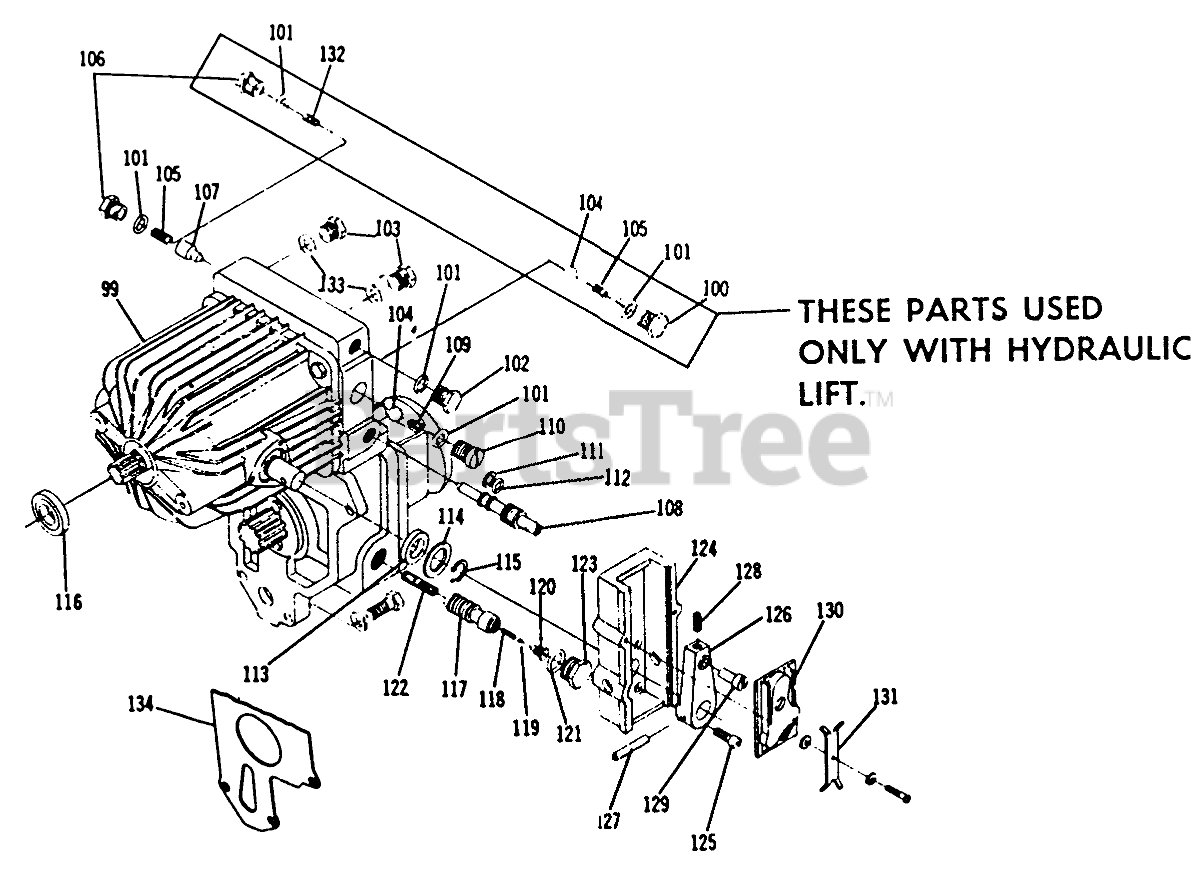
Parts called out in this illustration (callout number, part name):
99	SRV BULLT 437B
101	O RING
111	O-RING
126	Arm-Cam Follower
128	Set Screw-1/4-20 x 1/2
130	CAM
131	Screw #8-32 x 1/2
131	Lockwasher
131	Washer
133	O RING
133	RING BACKUP
134	GASKET
